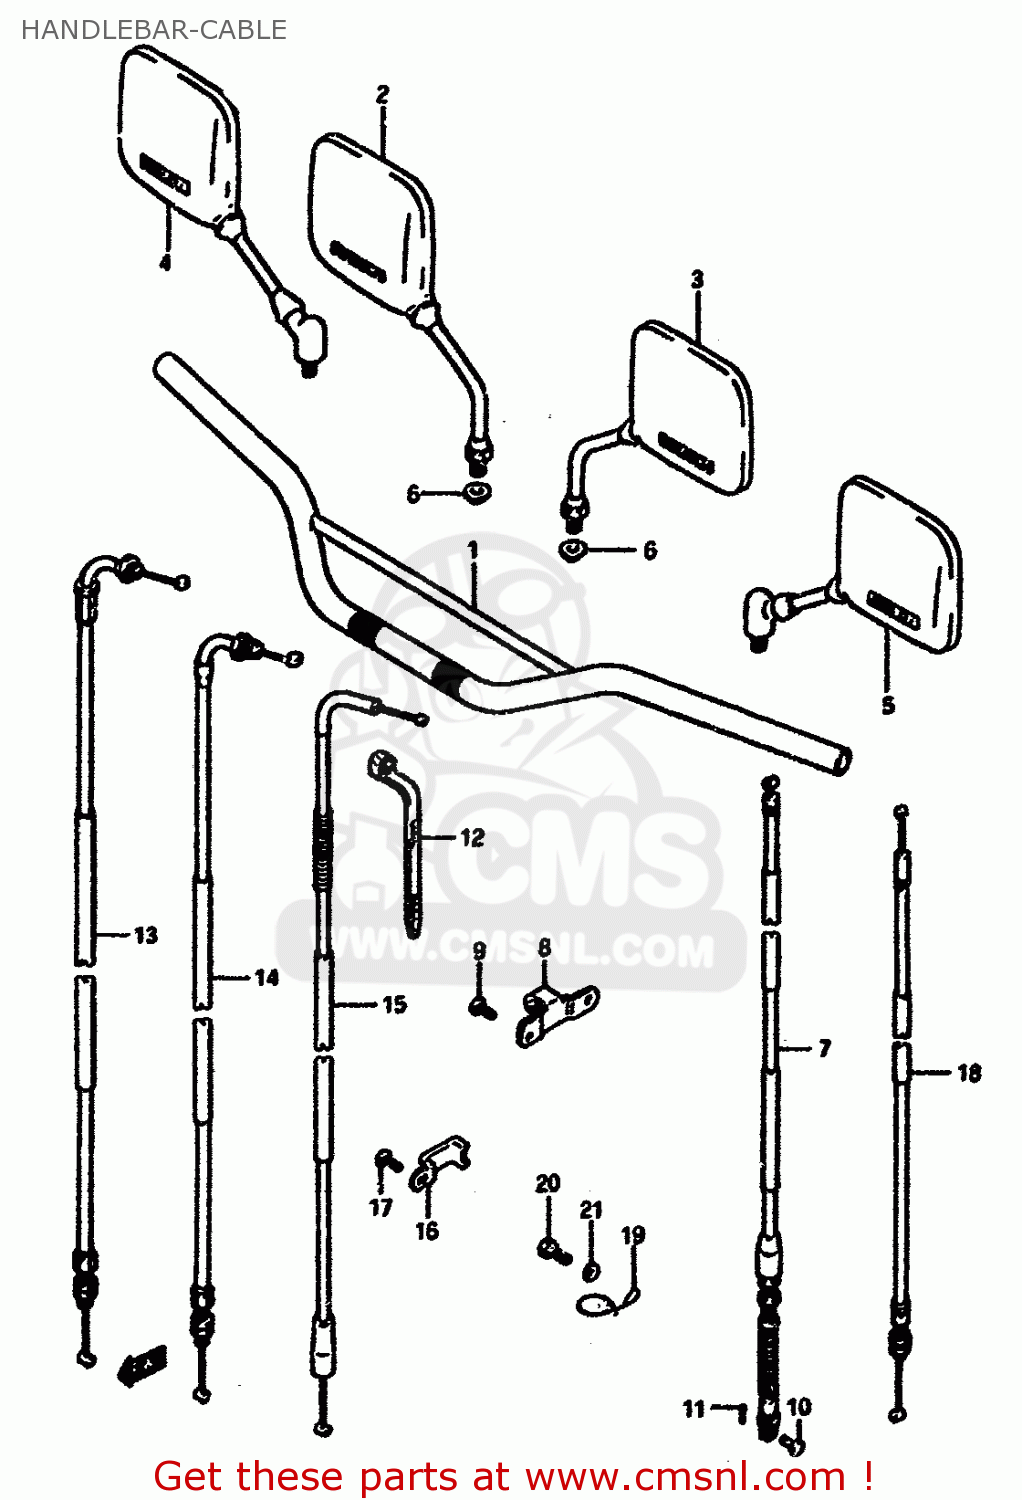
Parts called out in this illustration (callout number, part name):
1	HANDLEBAR
2	MIRROR, REAR VIEW RH
3	MIRROR ASSEMBLY,LEFT
4	MIRROR ASSEMBLY,REAR VIEW
5	MIRROR ASSEMBLY,REAR VIEW
6	WASHER
7	CABLE ASSY,CLUTCH
8	STOPPER,CLUTCH CABLE
9	SCREW
10	PIN(L:13)
11	PIN
12	CLAMP(L:125)
13	CABLE ASSY,THROTTLE NO.1
14	CABLE ASSY,THROTTLE NO.2
15	CABLE ASSEMBLY,THROTTLE
16	CLAMP
17	SCREW
18	CABLE ASSY,DECOMP
19	GUIDE
20	BOLT
21	WASHER,LOCK
